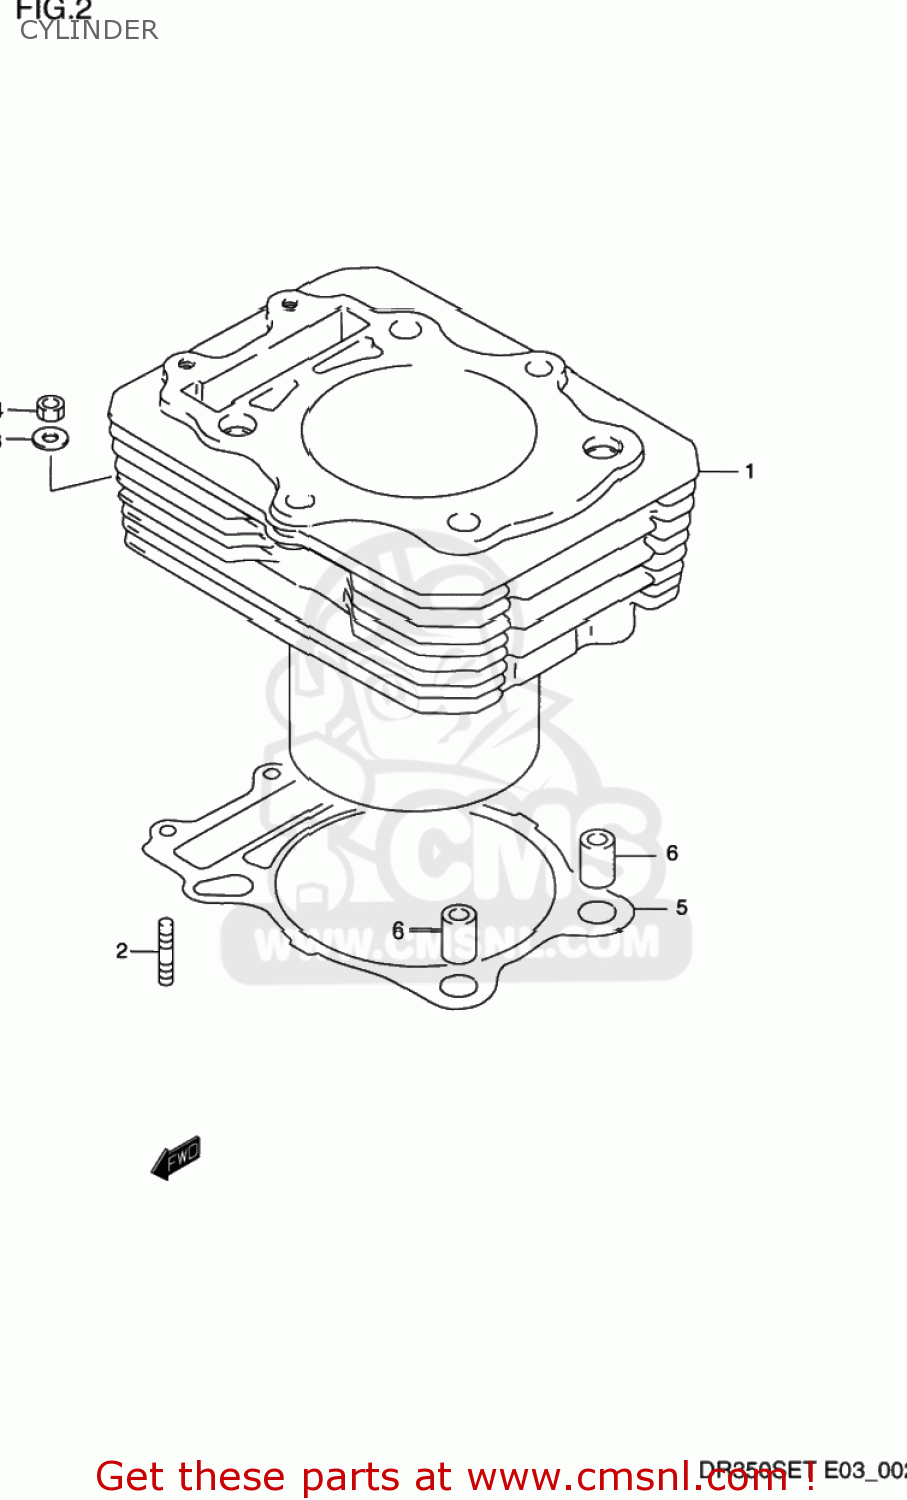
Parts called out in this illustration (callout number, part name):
1	CYLINDER
2	STUD 6X20
3	WASHER
4	NUT
5	GASKET,CYLINDER (NAS)
6	PIN
